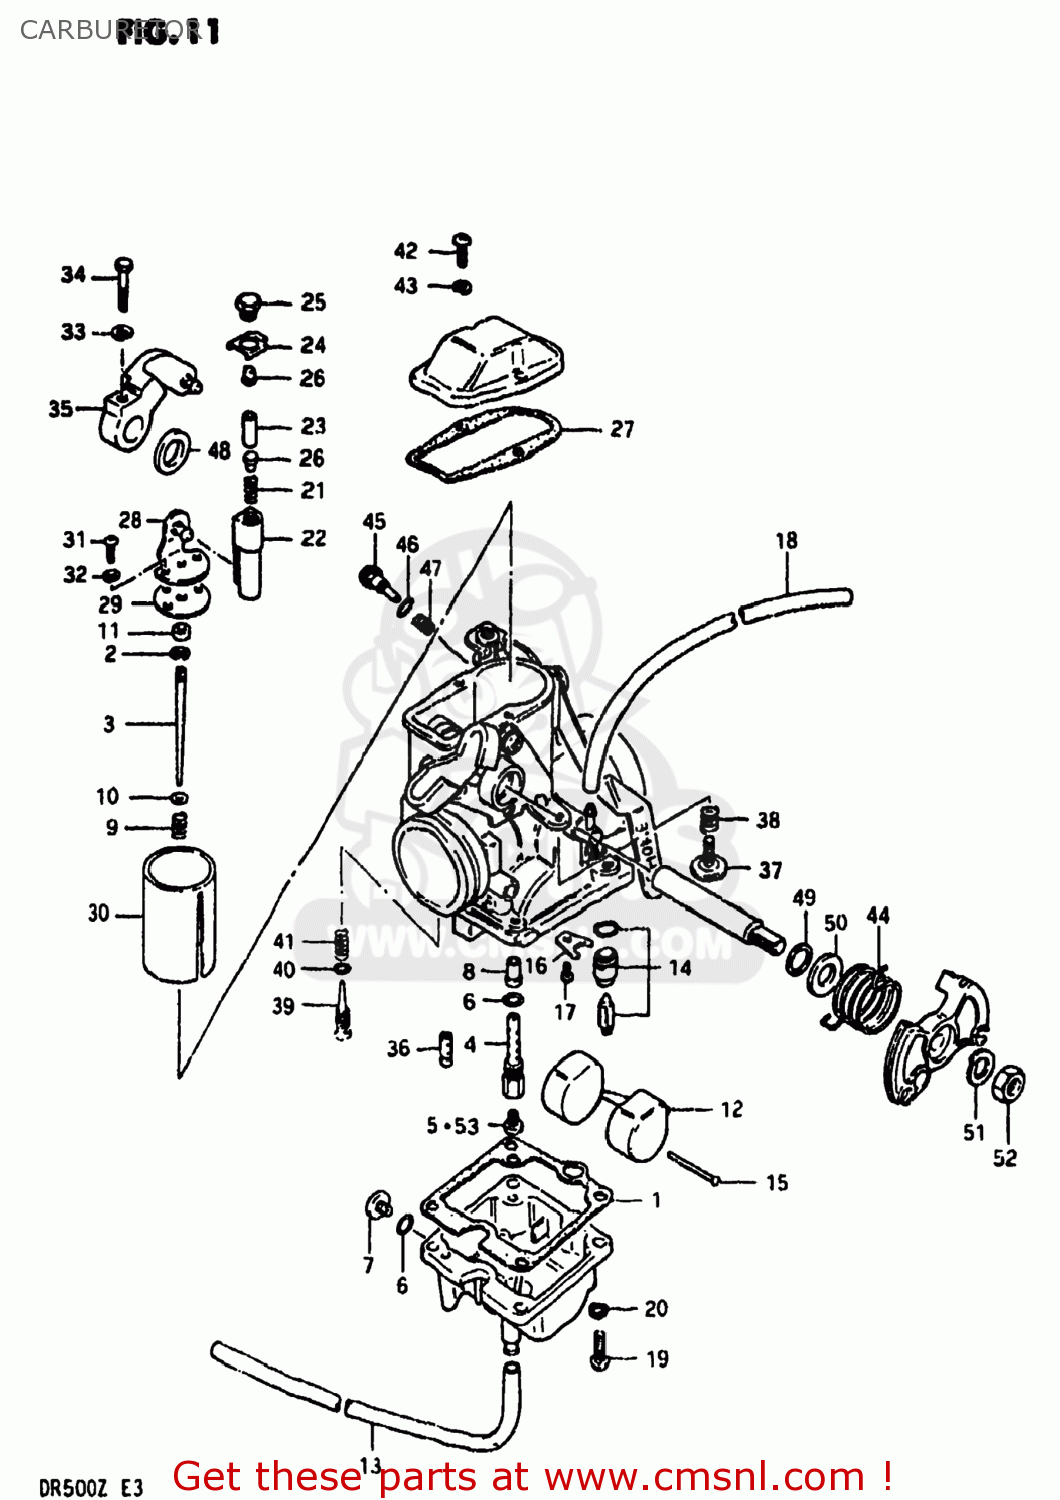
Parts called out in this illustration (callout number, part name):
1	GASKET,FLOAT CAHMBER (NAS)
2	CLIP
3	NEEDLE JET
4	PIPE,BLEEDER
5	JET,MAIN(132.5)
6	O RING
7	SCREW
8	JET,NEEDLE
9	SPRING
10	WASHER,JET NEEDLE
11	RING
12	FLOAT
13	HOSE
14	VALVE ASSY,NEEDLE
15	PIN,FLOAT
16	PLATE
17	SCREW 4X6
18	HOSE
19	SCREW
20	LOCK WASHER
21	SPRING,CARBURETOR
22	LEVER ASSEMBLY
23	SPRING
24	PLATE,CARBURETOR
25	SCREW
26	PIN,CARBURETOR
27	GASKET,MIXING CHAMBER (MCA)
28	CONNECTOR
29	PLATE,THROTTLE VALVE
30	VALVE,THROTTLE
31	SCREW
32	LOCK WASHER
33	WASHER
34	BOLT
35	ARM,THROTTLE
36	JET
37	SCREW
38	SPRING,THROTTLE SCREW
39	ADJUSTER,PILOT
40	O RING
41	SPRING,PILOT AIR SCREW
42	SCREW
43	LOCK WASHER
44	SPRING,THROTTLE VALVE
45	SCREW,PILOT AIR ADJUSTING
46	O RING
47	SPRING
48	RING
49	SEAL
50	RING
51	LOCK WASHER
52	NUT
53	JET
